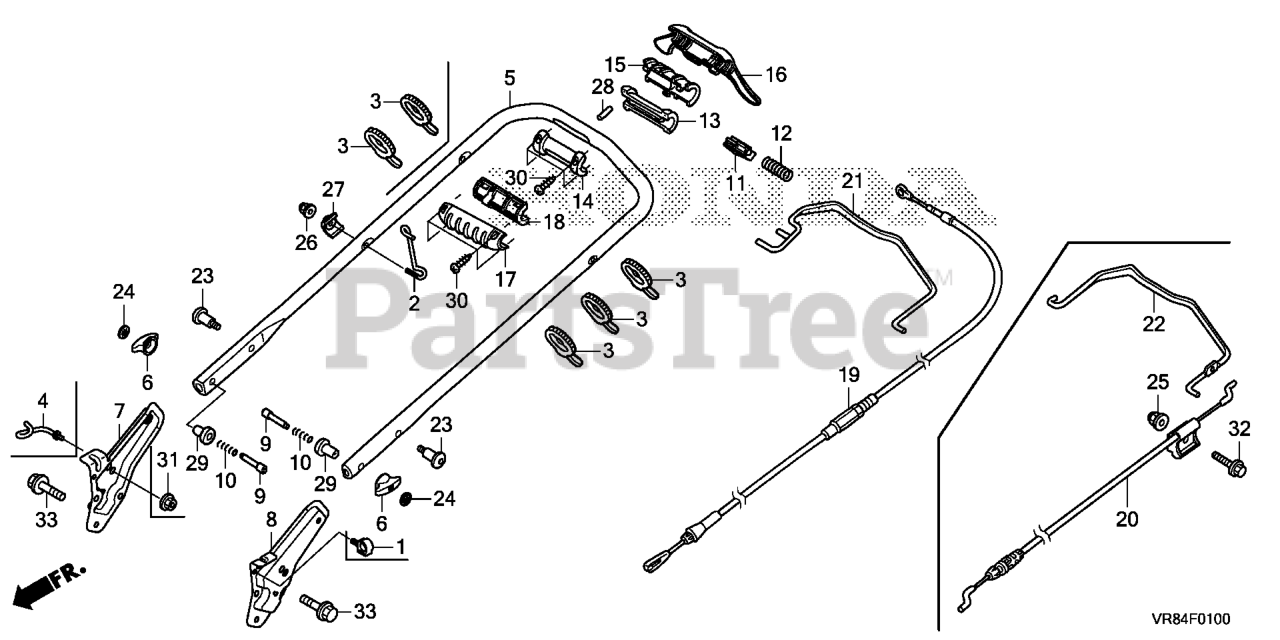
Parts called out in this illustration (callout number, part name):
2	GUIDE, ROPE
3	TIE, CABLE (157.5MM)
5	PIPE, HANDLE *NH105* (MAT BLACK)
6	GRIP, HANDLE JOINT *NH164* (GRIP GRAY)
7	STAY, R. HANDLE
8	STAY, L. HANDLE
10	SPRING, HANDLE ADJUSTING
11	LEVER, SELECT
12	SPRING, SELECT LEVER
13	BRACKET, GRIP (UPPER)
14	BRACKET, GRIP (LOWER)
15	COVER, BRACKET (UPPER)
16	GRIP, CLUTCH (UPPER) *NH164* (GRIP GRAY)
17	GRIP, CLUTCH (LOWER) *NH164* (GRIP GRAY)
18	COVER, BRACKET (LOWER)
19	CABLE, CLUTCH
20	CABLE, BRAKE
22	LEVER, BRAKE *NH105* (MAT BLACK)
23	BOLT, SPECIAL (8X30)
24	NUT, PUSH (5MM)
25	NUT, NYLON LOCK (6MM)
26	NUT, NYLON LOCK (6MM)
27	WASHER, FRAME JOINT
28	ROLLER (5X37.3)
29	COLLAR, HANDLE HEIGHT ADJUSTING
30	SCREW, TAPPING (4X12)
32	BOLT, FLANGE (6X45)
33	BOLT, FLANGE (8X14)
